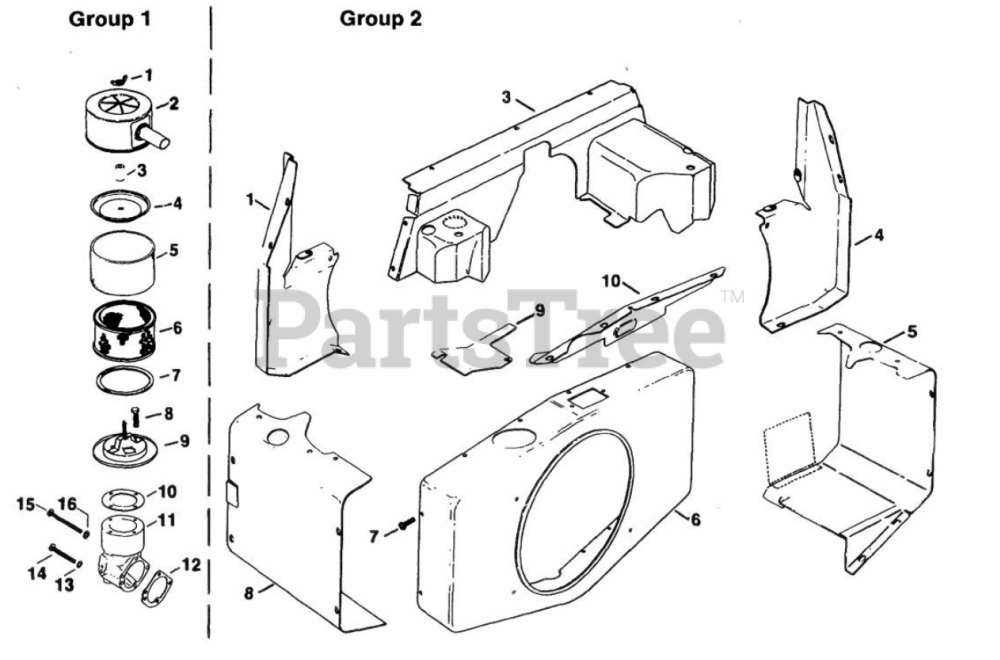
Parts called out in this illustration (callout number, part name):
2	Washer
3	Cover Cylinder Valve
4	Gasket-Cover
5	Stud-#2 Cyl Valve Cover
6	Hose-Breather
7	Cover-#1 Upper Cyl. Valve
8	Filter
9	Seal-Breather
10	Valve-Breather
11	Cover-#1 Lower Cyl. Valve
